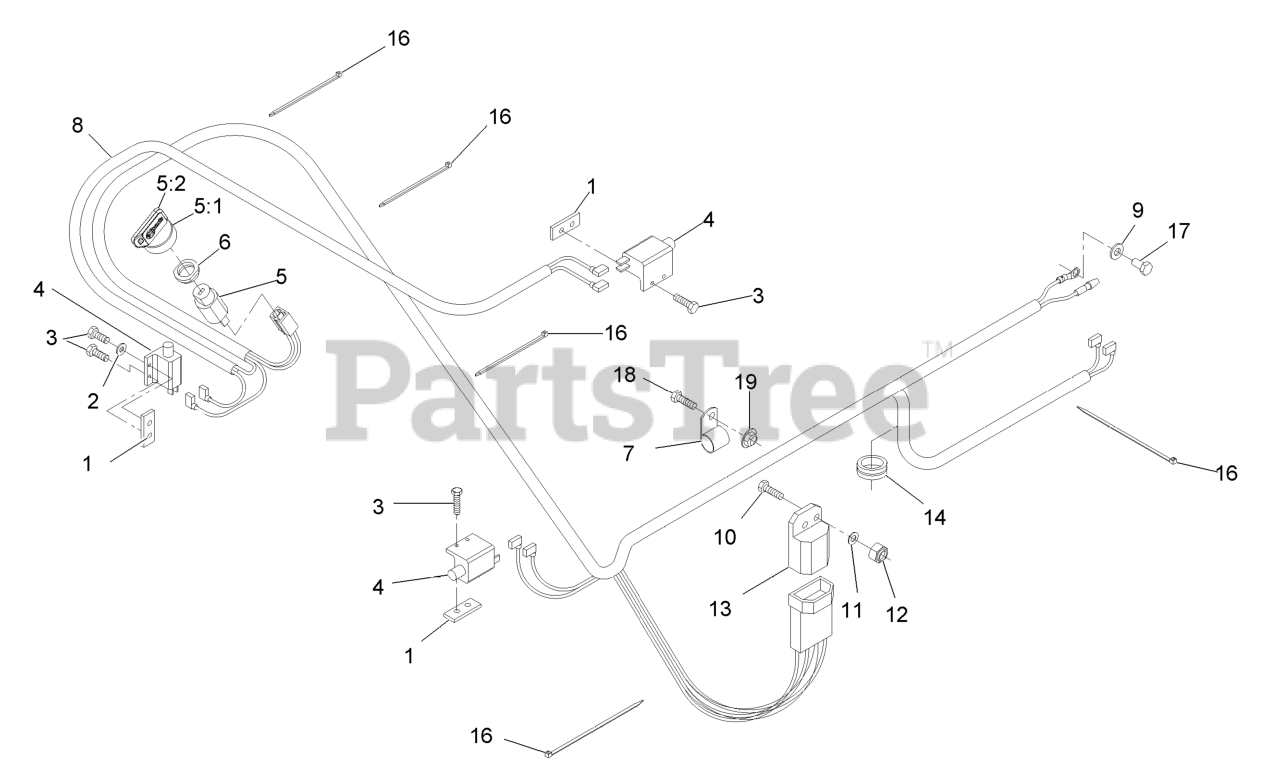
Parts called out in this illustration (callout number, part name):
1	PLATE-TAPPED
2	WASHER-FLAT
3	SCREW-PPH
4	SWITCH-OPEN, NORMALLY
5	SWITCH & KEY (INCLUDES NU
5:1	KEYS-IGNITION (SPARE PAIR
5:2	KEY-IGNITION
6	NUT-SWITCH, IGNITION
7	CLIP-LOOM
8	HARNESS-WIRING
9	WASHER-PLAIN
10	SCREW-HH
11	WASHER-FLAT
12	NUT-LOCK, NI
13	MODULE-INTERLOCK
14	GROMMET
16	TIE-CABLE
17	SCREW-HH
18	SCREW-HH
